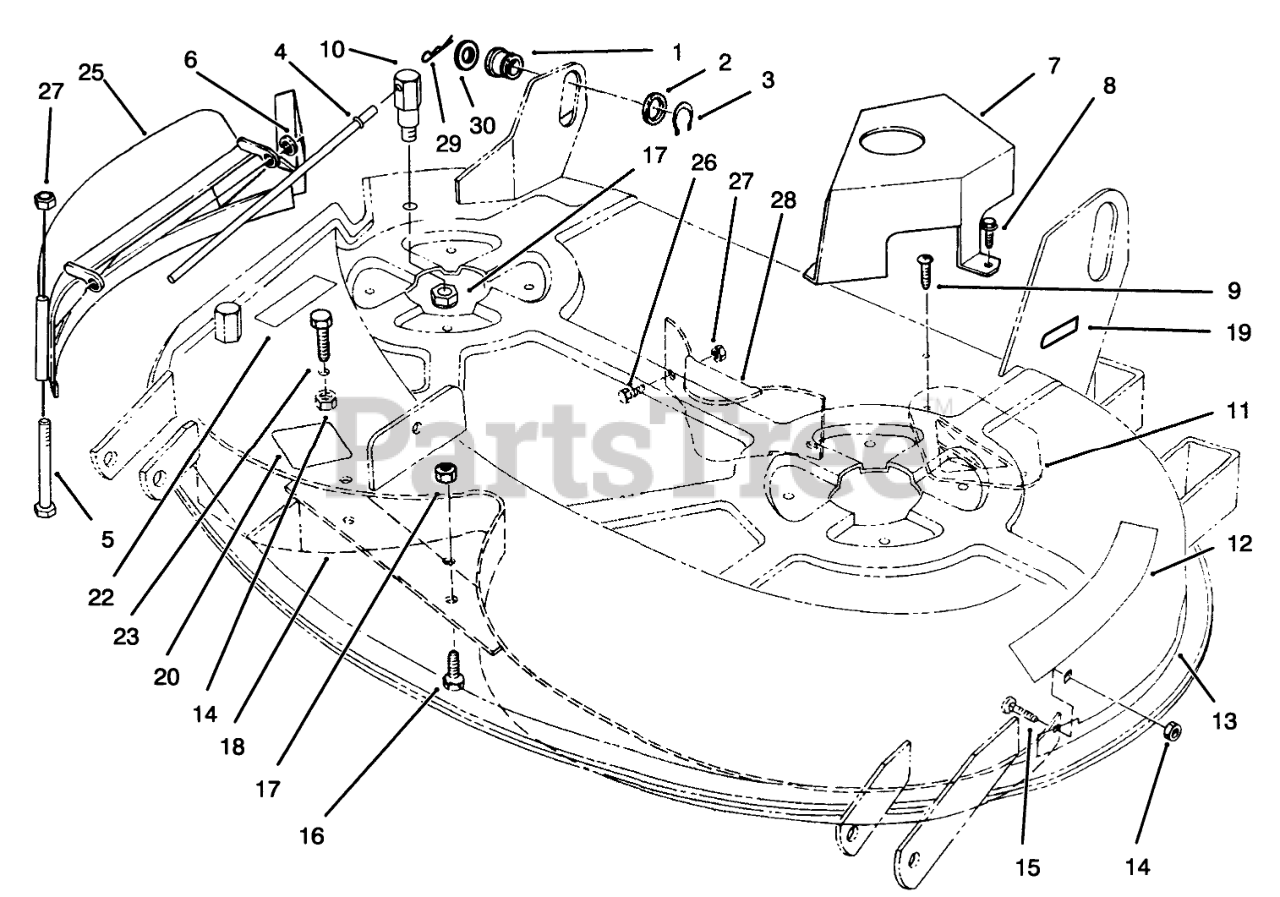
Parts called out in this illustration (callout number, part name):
1	Roller-Lift
2	Washer
3	RING-RETAINING
4	ROD-HINGE DEFLECTOR
5	SCREW-HH
6	WASHER-PLAIN
7	Cover-Belt
8	SCREW-HWHTF
9	SCREW-PPH
10	PIVOT POST - REAR
11	PLATE-KICKER
12	DECAL-DANGER
13	DECAL-RECYCLER DECK 38"
14	NUT-LOCK, NI
15	BOLT-CARR
16	SCREW-HH
17	NUT-LOCK, NI
18	BAFFLE ASM
19	DECAL-ATTACH-A-MATIC
20	Decal-Routing
22	DECAL-CAUTION
23	SCREW-HH
25	COVER-RECYCLER
26	SCREW-HH
27	NUT-LOCK, NI
28	BAFFLE ASM
29	Pin-Cotter
30	WASHER-FLAT
